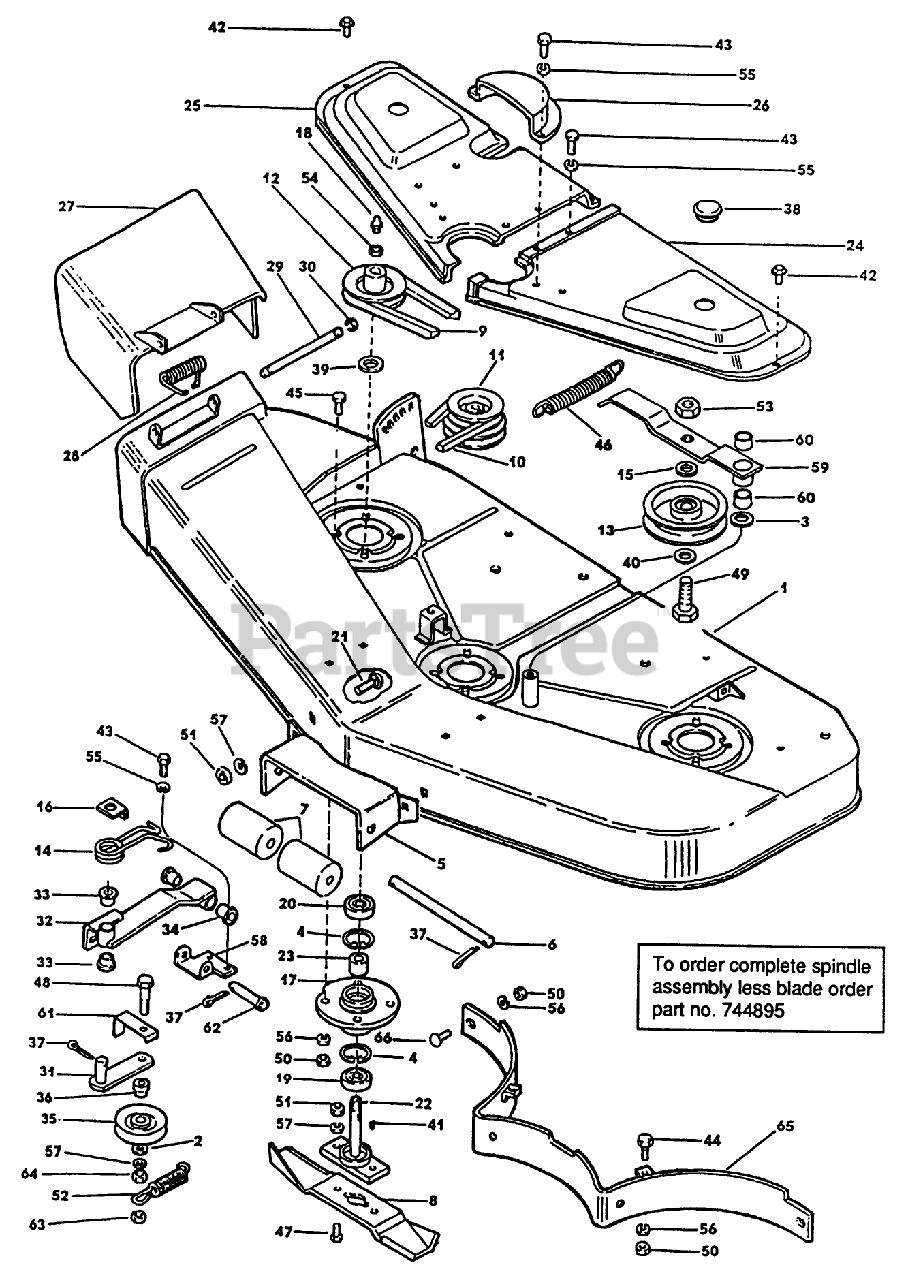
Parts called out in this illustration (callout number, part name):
2	WASHER
6	SHAFT
7	ROLLER
9	V-BELT
10	V-BELT (DRIVE)
13	PULLEY - IDLER
14	SPRING
17	HOUSING-SPINDLE S
22	SPINDLE ASSEMBLY
28	SPRING - CHUTE
29	SHAFT - CHUTE
30	E-RING
32	PIVOT ASSEMBLY
33	BUSHING
34	BUSHING
35	PULLEY - V-IDLER
36	SPACER
38	PLUG - BELT COVER
39	SPACER
42	SCREW-THREAD FRMG
43	SCREW-HH
44	SCREW - HEX
45	SCREW
46	SPRING
48	SCREW-HH
50	NUT SS
51	NUT
52	SPRING - TENSION *B
54	LOCKNUT-SPECIAL
57	WASHER
60	BEARING-SLEEVE
61	GUIDE - BELT
62	PIN - CLEVIS
63	NUT
64	NUT-HEX JAM
